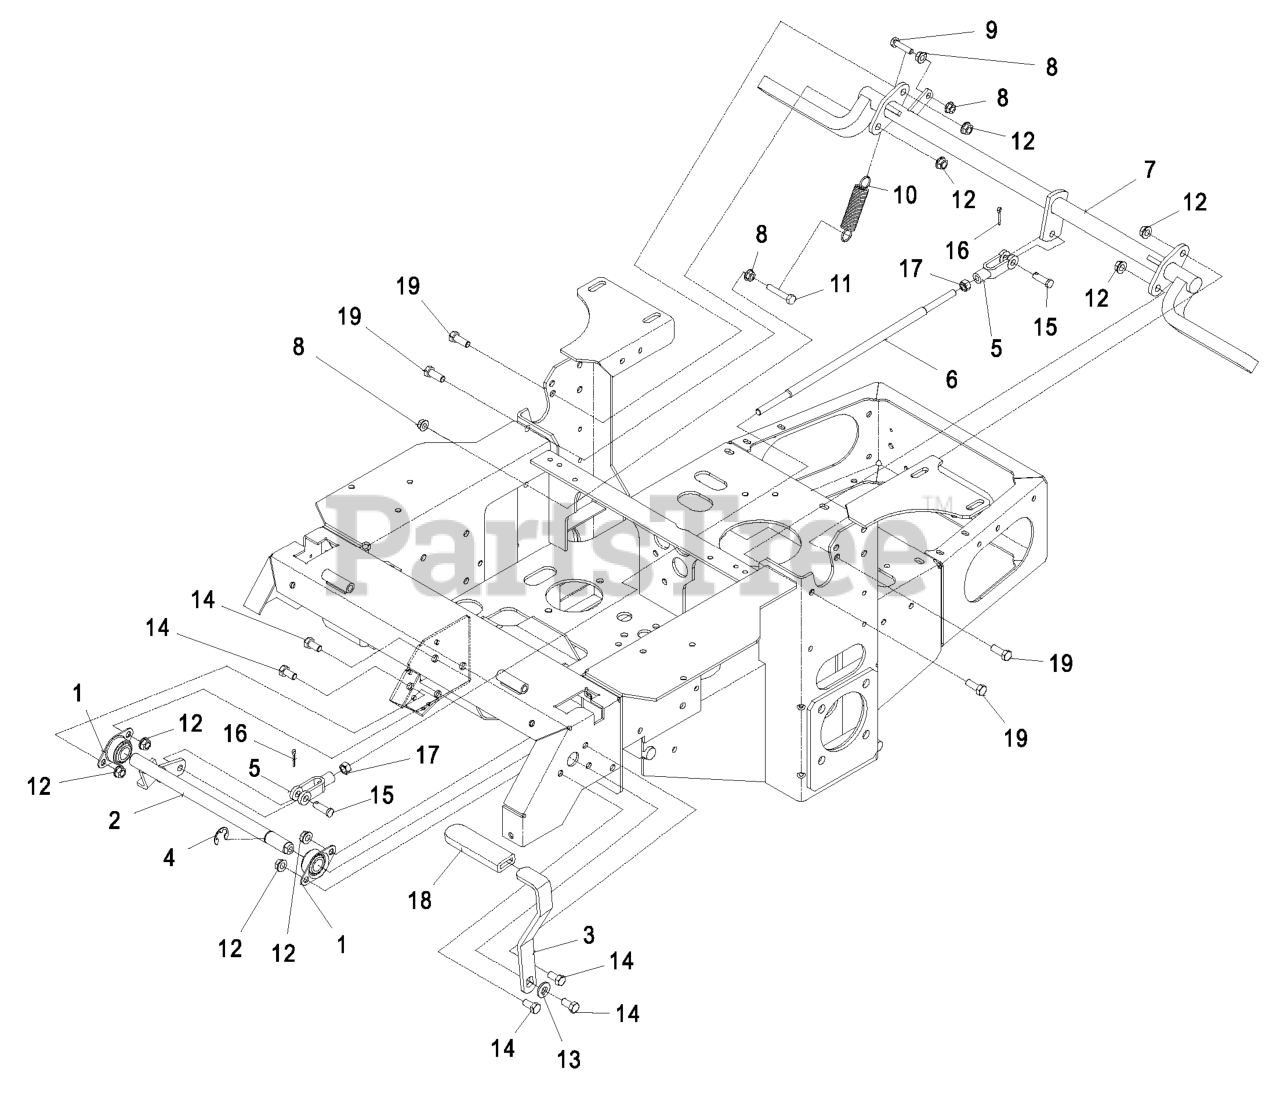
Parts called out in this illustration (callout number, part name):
1	BEARING-FLANGE, SIDE
2	SHAFT-BRAKE, PARKING
3	ASM,BRAKE HANDLE W/ GRIP
5	YOKE-LINKAGE, BRAKE
6	LINKAGE-HANDLE, BRAKE
9	SCREW-HH
10	SPRING-IDLER
11	SCREW-HH
12	NUT-HHF, WHIZ
13	WASHER-BELLEVILLE
14	SCREW-HH
15	PIN-CLEVIS
16	PIN-COTTER
17	NUT-HEX
18	GRIP-LEVER
19	SCREW-HH
